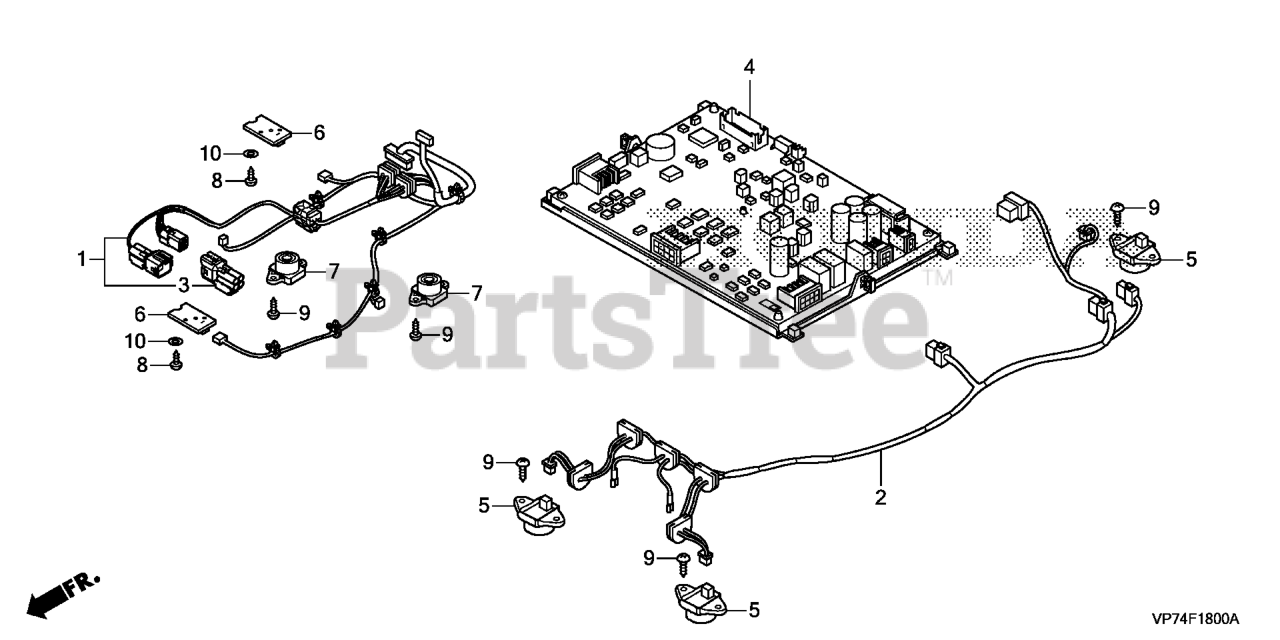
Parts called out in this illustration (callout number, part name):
1	WIRE HARNESS ASSY., MAIN
2	SUB-WIRE HARNESS ASSY.
3	CONNECTOR, DUMMY (4P)
4	CONTROL UNIT, ELECTRONIC
4	ECU ASSY. (310)
5	SENSOR ASSY., AREA
6	SENSOR, OBSTRUCTION
7	SENSOR ASSY., LIFT
8	SCREW, TAPPING (4X10)
9	SCREW, TAPPING (4X12)
10	WASHER, PLAIN (4MM)
